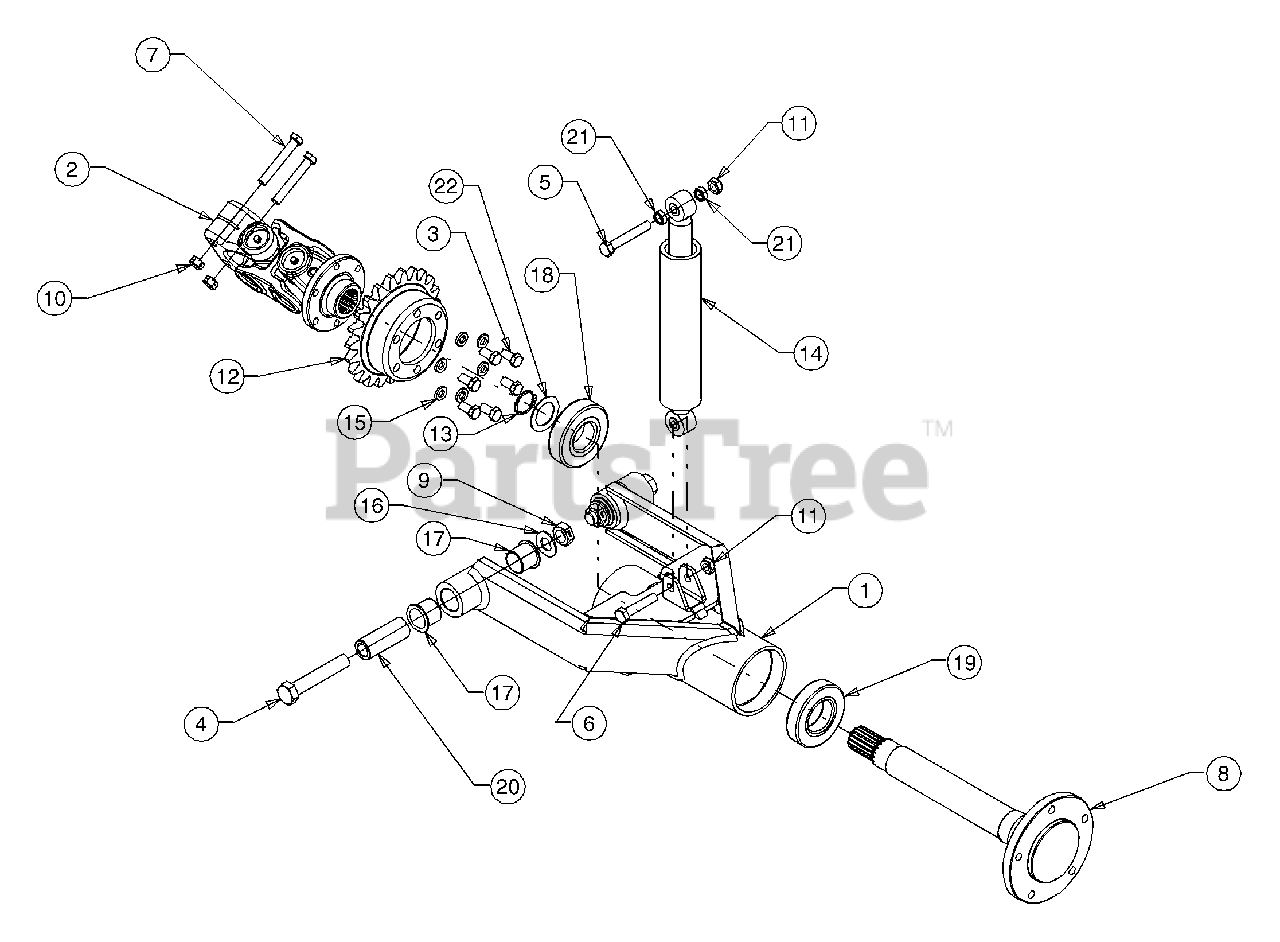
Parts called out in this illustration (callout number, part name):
1	Axle Support Assembly, Center Weld
2	Weld Coupling Assembly
3	Screw, Hex, 3/8-16 x .75, Gr5
4	Screw, Hex, 5/8-18 x 3.5, Gr5
5	Screw, M10-1.25 x .65, Gr8
6	Screw, M10-1.25 x .50, Gr8
7	Screw, Hex, 3/8-16 x 2.5, Gr5
8	Axle Shaft, Drive Center
9	Nut, Jam, 5/8-11
10	Nut, Hex Lock, 3/8-16
11	Nut, Nylon Lock, M10 x 1.25
12	Sprocket, Hub, 1.75 - 23T
13	Retaining Ring, External, 1.14
14	Shock Absorber, 2.88 Stroke
15	Washer, Lock, 3/8 , Regular Duty
16	Washer, Flat, .65 x 1.25 x .075
17	Bearing, Flange, 1.0 x 1.125 x 1.0
18	Ball Bearing, Internal Axle
19	Ball Bearing, External Axle
20	Spacer, .63 x 1.0 x 2.594
21	Spacer, Shock
22	Spacer, 1.78 x 1.88
